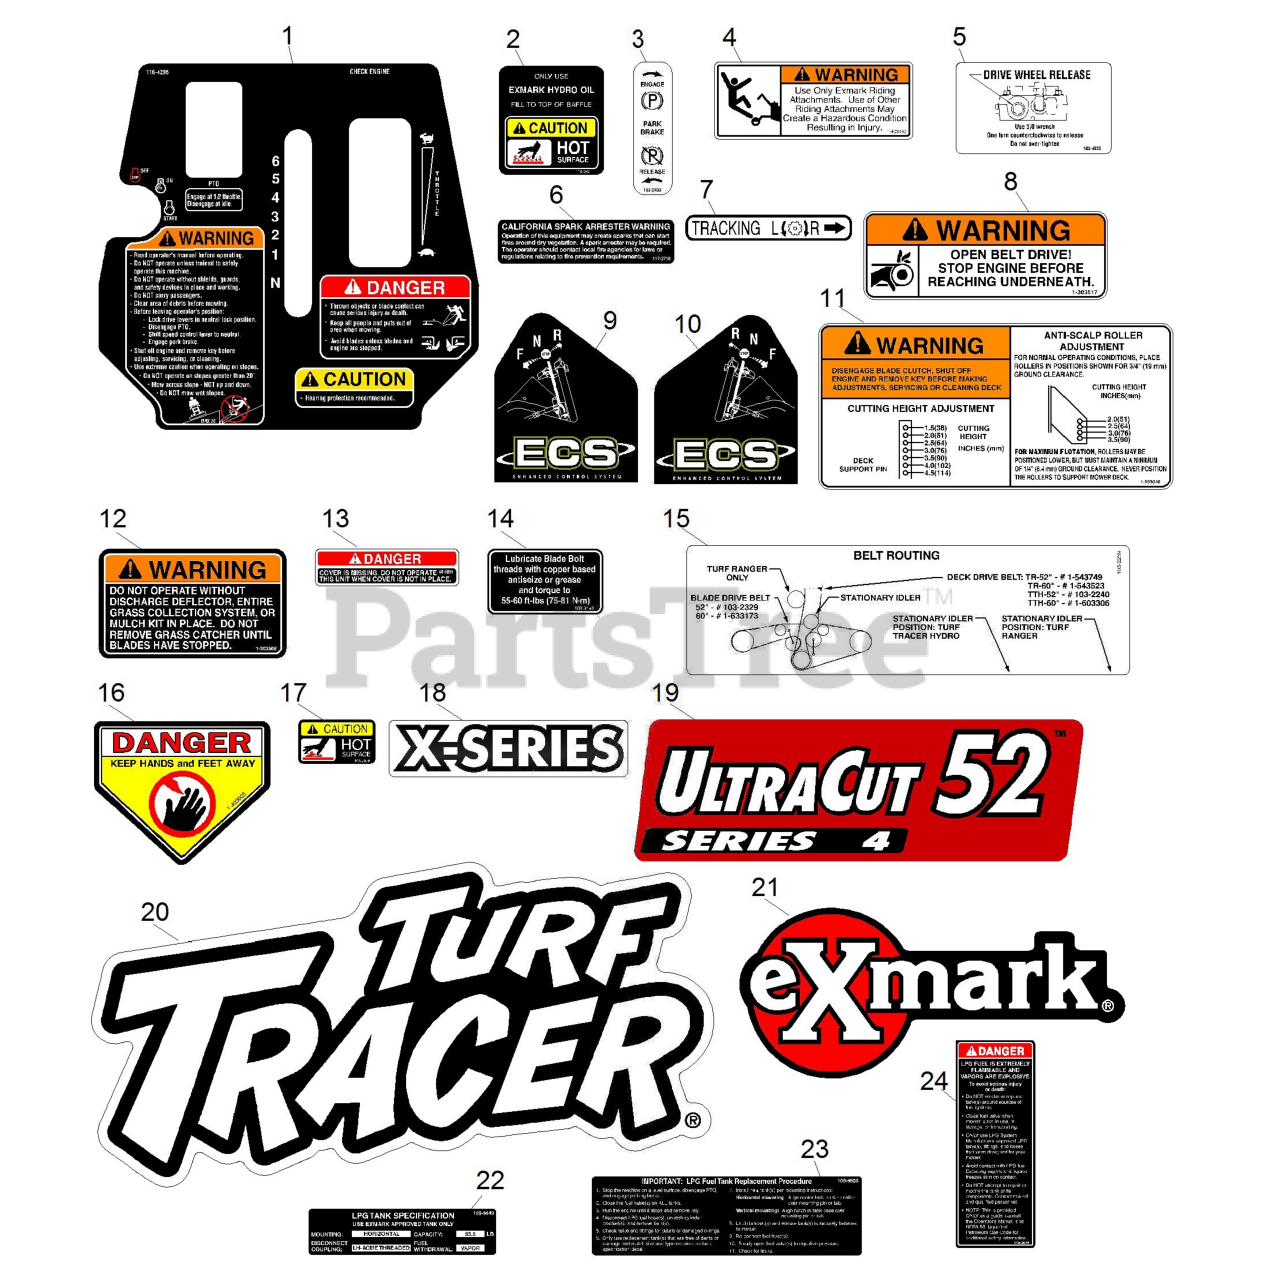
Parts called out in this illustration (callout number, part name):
1	DECAL,CONSOLE TTX
2	DECAL-HYDRAULIC TANK
3	DECAL,PARKING BRAKE
4	DECAL,SULKY WARNING
5	DECAL,DRIVE RELEASE
6	DECAL-ARRESTER, SPARK
7	DECAL,TRACKING ADJUST
8	DECAL,BELT DRIVE
9	DECAL,LH ECS INSTRUCTION
10	DECAL,RH ECS INSTRUCTION
11	DECAL,ANTI SCALP
12	DECAL-WARNING, DISCHARGE
13	DECAL-COVER, MISSING
14	DECAL,BOLT TORQUE
15	DECAL,BELT ROUTING
16	DECAL-DANGER
17	DECAL-CAUTION
18	DECAL-X-SERIES
19	DECAL,ULTRACUT 52 SERIES
20	DECAL,TTH MODEL
21	DECAL,EXMARK LOGO
22	DECAL,LPG TANK SPEC HORIZ
23	DECAL-TANK REPLACEMENT
24	DECAL-LPG WARNING
